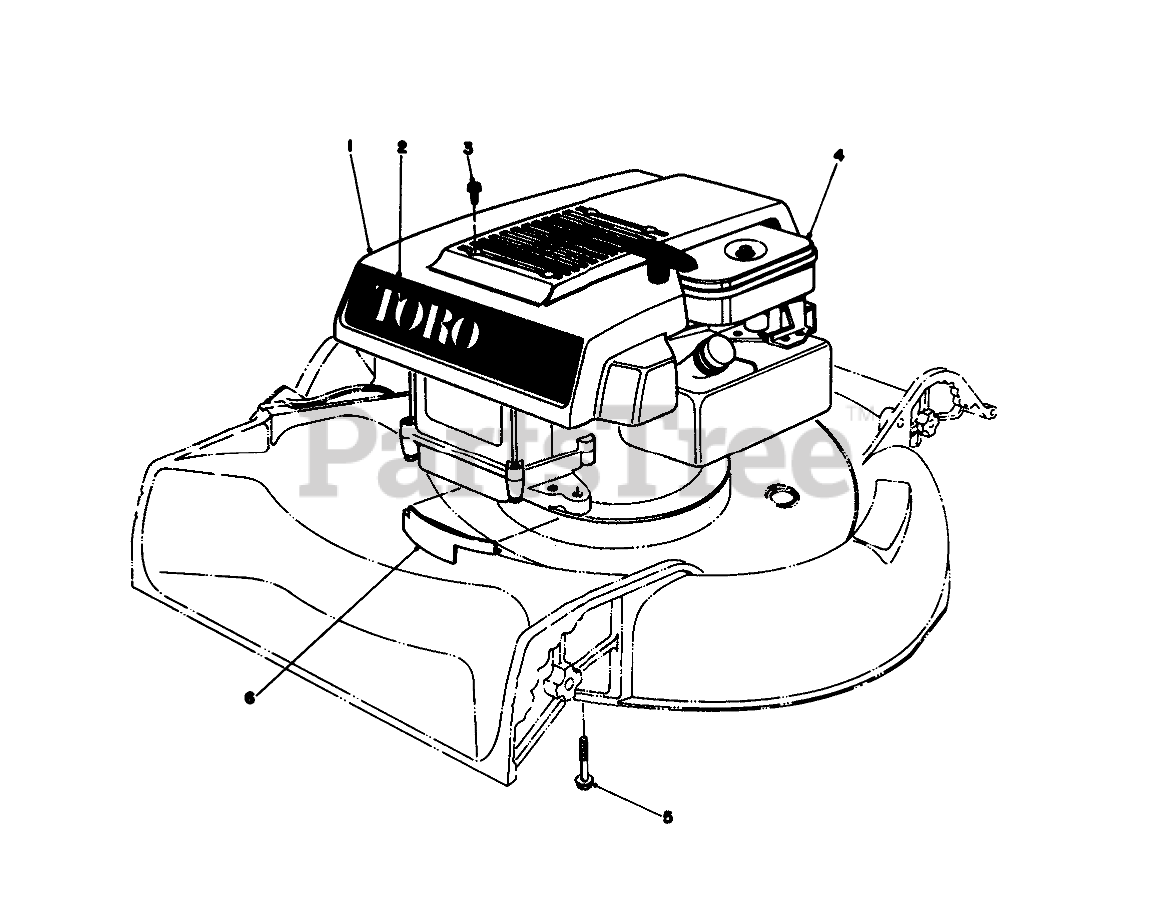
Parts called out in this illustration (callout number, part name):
1	SHROUD
2	Decal-Toro
3	8X1/2 SELF TAP SCREW
4	Engine (Model 16067)
5	3/8-16 X 2-3/4 CAPSCR
6	HOUSING CAP
